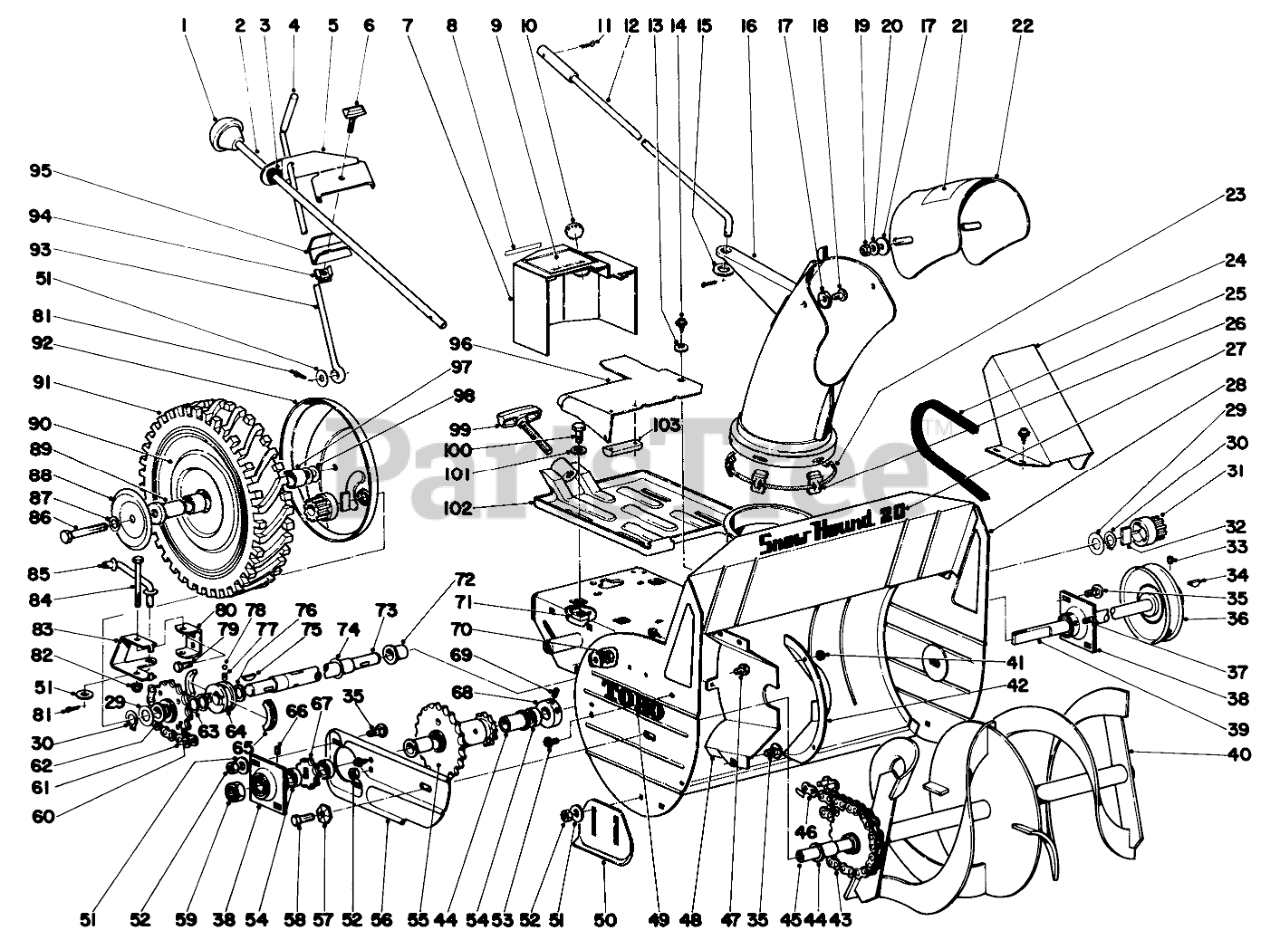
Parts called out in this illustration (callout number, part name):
2	Control Rod Upper Chute
3	Grommet
5	Bracket-Control
6	Clamp Assembly
7	Shroud-With Decal
8	Decal Choke
9	Decal-Start & Choke Inst.
10	Plug Button
11	PIN-COTTER
12	Rod-Chute
13	Washer
14	10-16 X 3/8 THDG SCREW
15	WASHER-FLAT
16	Chute
17	Washer
18	SCREW-PPH
19	Nut
20	WASHER-FLAT
21	Decal
22	Deflector
23	Garter Spring
24	Shroud Belt
27	Decal
28	Frame Incl. Ref. #72
29	Washer
30	Snap Ring
31	Pinion Kit
32	RATCHET DOG
33	SCREW-SET, HSH
34	KEY-WOODRUFF
35	Bolt
36	Pulley
37	SCREW-SQH
38	Bushing Flange Mounted
39	Drive Shaft
40	Rotor Incl. Ref. #44
41	NUT-LOCK, NI
42	Guard-Rotor Chain
43	Chain
44	Bushing
45	ROTOR SHAFT
46	LINK-CONNECTING
47	SCREW-HH
48	Guard, Chain
49	Decal
50	Skid
51	WASHER-FLAT
52	Nut
53	SCREW-SHWH
54	COSHAFT SPACER
55	Sprocket (Incl. Ref. 7)
56	Support-Bearing
57	LOCKWASHER-PYRAMID
58	SCREW-HH
59	NUT-LOCK, NI
60	Drive Sprocket Assembly
61	Chain
62	BUSHING-FLANGE
63	Thrust Washer
64	Sliding Jaw
66	SCREW-SET, HSH
67	Sprocket
68	Collar
69	SCREW-HSH
70	Locknut
72	Bushing
73	Drive Shaft
74	Washer
75	KEY-WOODRUFF
76	5/8X039 EX HD RING
77	Spring
78	BALL-STEEL
79	SCREW-HH
80	Pivot Support
81	PIN-COTTER
82	Nut
83	Fork Shift
84	SCREW-HH
85	Link Shift
86	SCREW-HH
87	WASHER-LOCK
88	Hub Cap
89	Spindle Wheel
90	Wheel Incl. Ref. #97
92	Wheel Cover
93	Control Rod Traction
94	Retaining Nut
95	Strap, Clamp
96	Chain Guard
97	BUSHING
98	WASHER
99	Clamp Assy.
100	SCREW-HH
101	WASHER-PLAIN
102	Adapter Plate
103	Chain Guide
